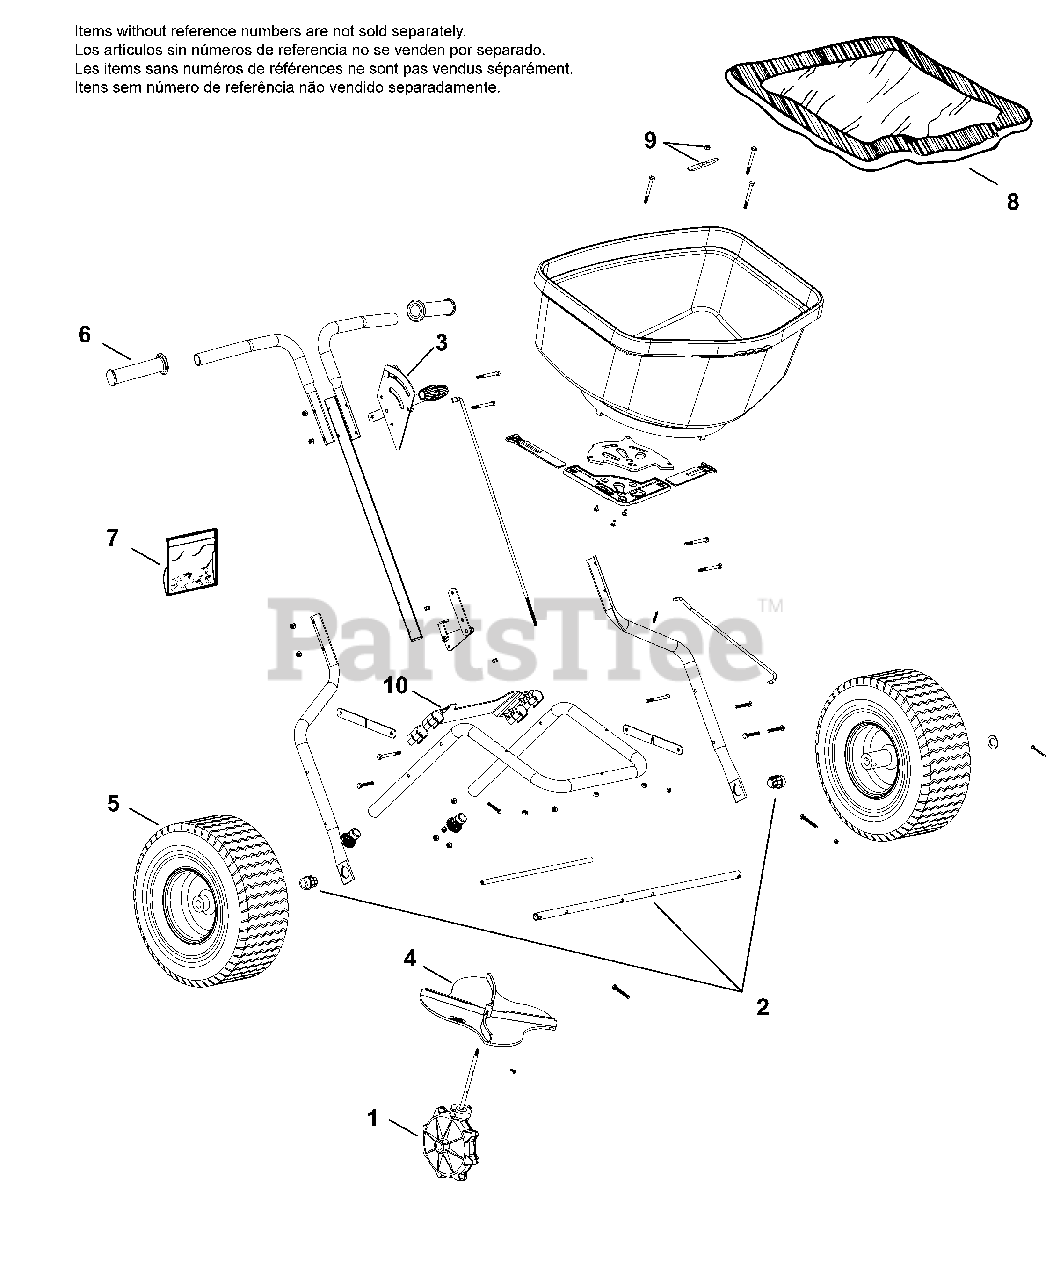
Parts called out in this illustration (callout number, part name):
1	GEAR BOX ASSEMBLY
2	DRIVE SHAFT W/2 BUSHINGS
3	GATE CONTROL ASSEMBLY, SS
4	IMPELLER & SECURING SCREW ASSEMBLY
5	RB-100 TIRE & RIM ASSEMBLY 14”
6	HANDLE GRIPS
7	HARDWARE BAG, SS
8	RAIN COVER
9	AUGER & LOCK NUT ASSEMBLY
10	REAR BAFFLE
